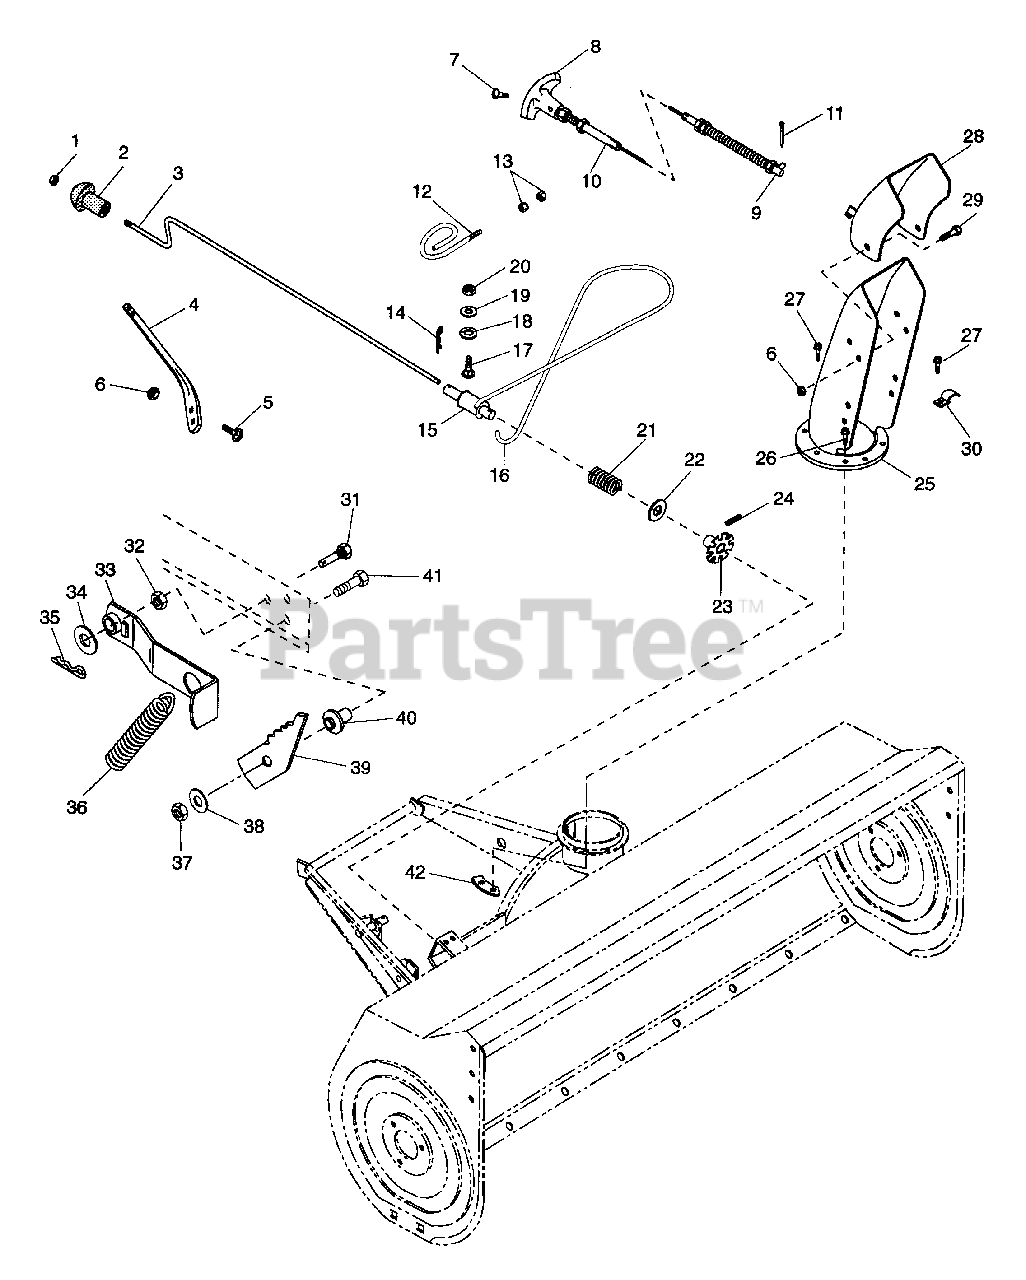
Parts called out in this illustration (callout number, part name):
1	NUT-LK-JAM-CTR .375-16 PL
3	CHUTE CONTROL CRANK
4	CHUTE SUPPORT
5	BLT-RDHDSQNK .38-16X1.0 PL
6	NUT-LK-CTR .375-16 GR A PL
7	SCR-MCH 8-32X.75 SLPAN PL
8	KNOB-BLACK
10	CONTROL CABLE
11	PIN-COTR .09X.75 PL
12	CABLE SUPPORT
13	NUT-LK-FLG .250-20 PL
14	PIN-HAIR INT .08X.38X1.42 YWZC
15	SPOOL
17	BLT-RDHDSQNK .25-20X.75 GR5PL
18	WSHR-FL-STL.281X.62X.065 PL
19	WSHR-LK .313X.062
20	NUT-HEX .250-20 PL
21	SG-COMP .054X.75X1.6
22	WSHR-FL-STL .640X1.005X.062 PL
23	DISC ASSEMBLY
24	PIN-ROLL .188X1.00
25	DISCHARGE CHUTE
26	SCR-TAP 12-24X.50 TORX YWZC TR
27	SCR-TAP 12-24X.75 HWH PL TR
28	DEFLECTOR W/DECAL
29	BLT-HEX .38-16X.75 PL GR2
30	CABLE CLAMP
31	STUD-WEIGHT
32	NUT-LK-CTR .50-13
33	SPRING ARM
34	WSHR-FL-STL .458X.750X.06 PL
35	PIN-HAIR INT .08X.18X1.18
36	SG-TENS .188X1.50X8.5 WLD 57
37	NUT-LK .312-18 GR A PL
38	WSHR-FL-STL .38X.875X.083 PL
39	SPRING ASSIST CONTROL
40	SPACER .323X.498X.531X1.000
41	BLT-HEX .31-18X1.25 PL GR2
42	CHUTE CLAMP
